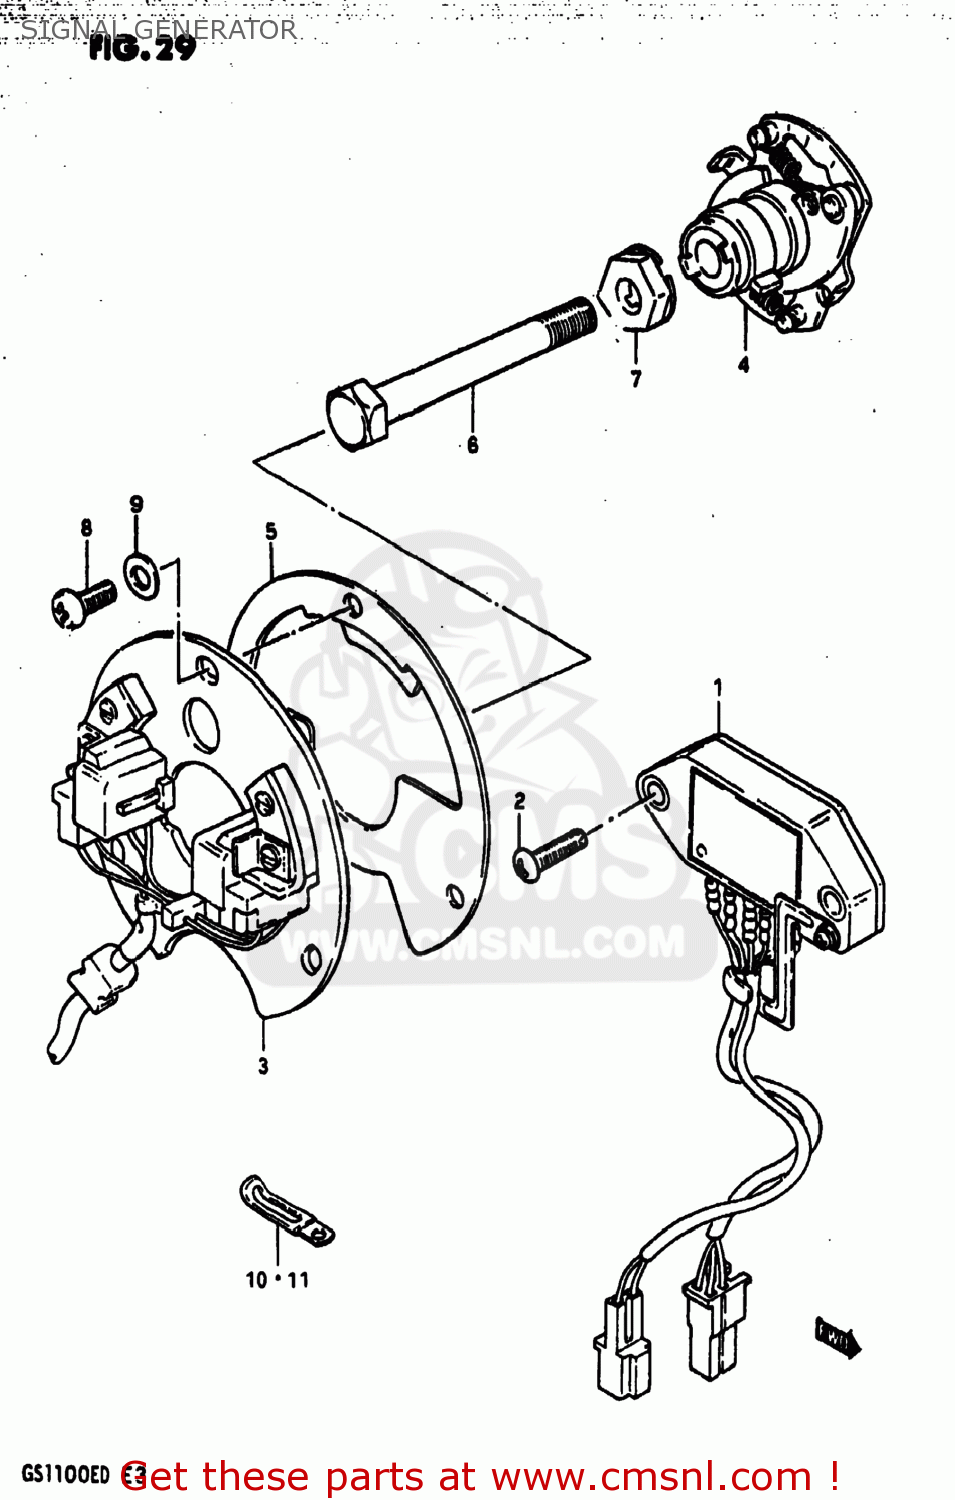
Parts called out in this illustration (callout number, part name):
1	IGNITER UNIT
2	SCREW
3	SIGNAL GENERATOR ASSEMBLY
4	GOVERNOR ASSEMBLY
5	PLATE,TIMING
6	BOLT
7	WASHER
8	SCREW(5X12)
9	WASHER
10	CLAMP L:35
11	CLAMP
